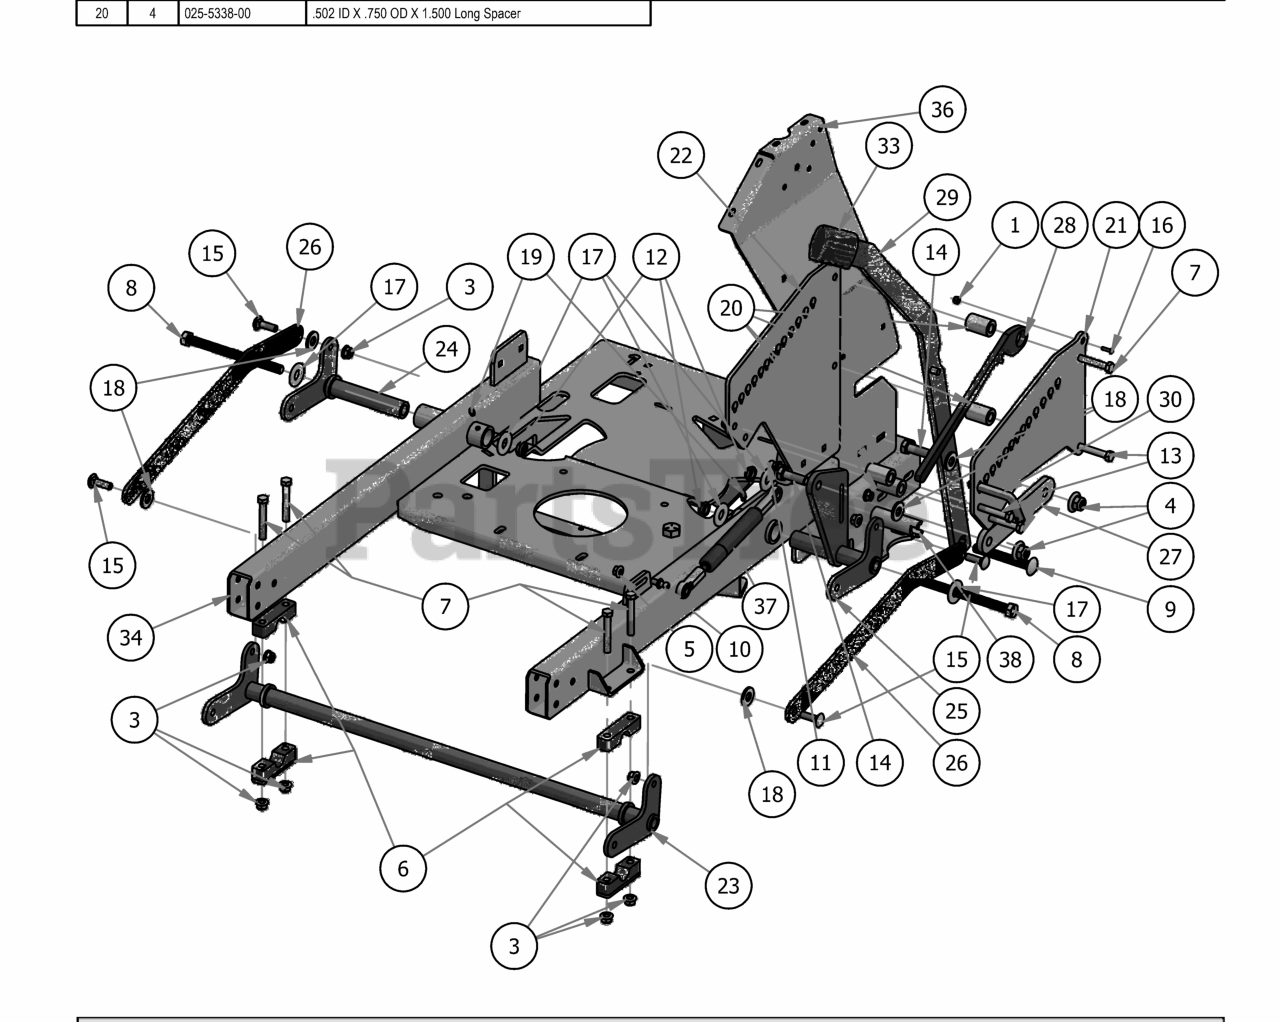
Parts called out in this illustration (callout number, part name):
1	10-24 Nylon Insert Locknut Zinc Orange Nylon
3	3/8" Nylock Flange Nut
4	1/2-13 Nylon Flange Nut
5	5/16" Flange Nut
6	Pillow Block Kit
7	3/8-16 x 2 1/2" Hex Bolt
8	1/2-13 x 6 1/2 Hex Bolt
9	1/2-13 x 4" Carriage Bolt
10	10mm Damper Ball Stud-Steering
11	10mm Damper Ball Stud-XP Linkage
12	1/2" Nylcock Nut (1/2 Jam)
13	3/8-16x3 grade 5 hex bolt
14	1/2" x 1 1/2" Hex Bolt
15	3/8" x 1 1/4" Carriage Bolt
16	10-24 X 5/8 BS Button Head Bolt
17	1/2" Flat Washer
18	.505 Nylon Spacer
19	1/4" Press in Grease Fitting
20	.502 ID X .750 OD X 1.500 Long Spacer
21	2019 Stand On Outer Adjustment Plate
22	2019 Stand On Inner Adjustment Plate
23	2019 Stand On Front Actuator Bar Weldment
24	2019 Stand On Actuator Bar Rear RH
25	2019 Stand On Actuator Bar Rear- LH
26	2019 Stand-on Actuator Linkage
27	2019 Stand On Lever Secondary Linkage
28	2019 Stand on deck lever lock
29	2019 Stand On Lift Lever Weldment
30	Height Adj Pin
33	2019 Stand On Lift Grip
34	2019 Stand On Frame Weldment
36	2019 Podium Panel Left
37	200 lb Gas Spring- 54" Deck outlaw
38	Lever Pivot Actuator Rod
